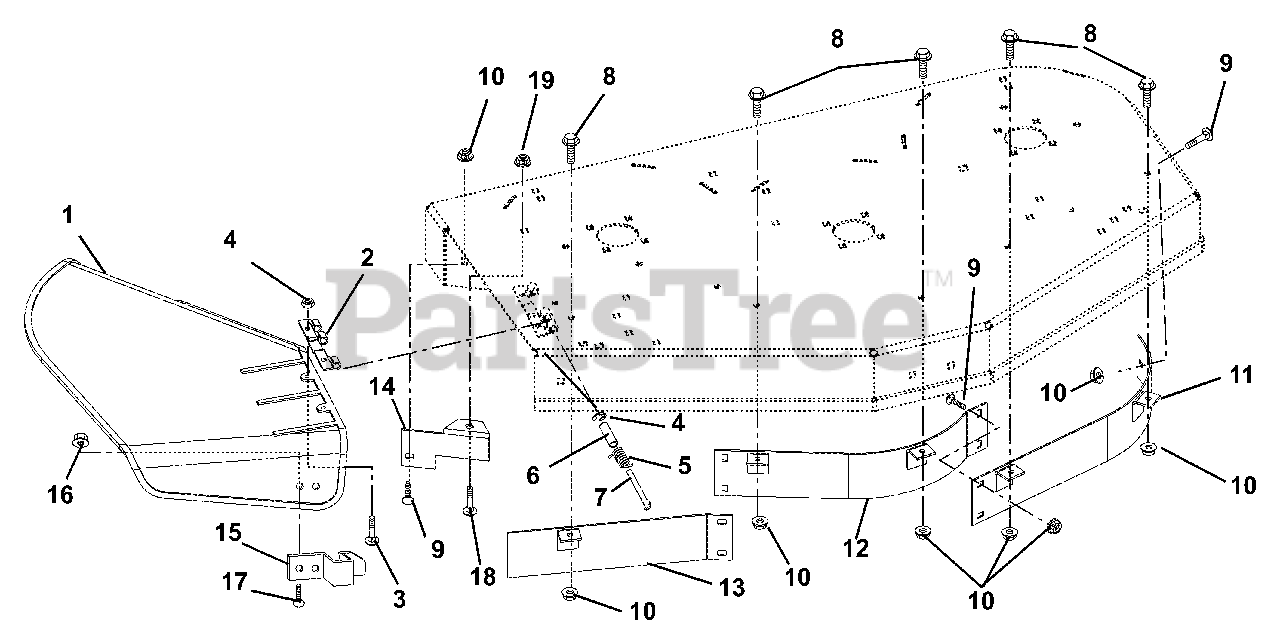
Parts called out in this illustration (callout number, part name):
1	Deflector, Chute
2	Hinge, Plate
3	Bolt, Round Head Square Neck .25-20 x .75 Grade 5
4	Ring, Retaining External .312 x .025
5	Spring, Torsion .095 x .50 x 1.00
6	Bushing, Sleeve
8	Bolt, Serrated Hex Flange Washer Head .31-18 x .75
9	Bolt, Round Head Square Neck .31-18 x .75
10	Nut-.312-18 Flange Nyloc
11	Weldment, Upper Left Baffle-40" (044)
11	Weldment, Upper Left Baffle-44" (046)
11	Weldment, Upper Left Baffle-48" (048)
11	Weldment, Upper Left Baffle-52" (050)
12	Weldment, Upper Center Baffle-40" (044)
12	Weldment, Upper Center Baffle-44" (046)
12	Weldment, Upper Center Baffle-48" (048)
12	Weldment, Upper Center Baffle-52" (050)
13	Weldment, Upper Right Baffle-40" (044)
13	Weldment, Upper Right Baffle-44" (046)
13	Weldment, Upper Right Baffle-48" (048)
13	Weldment, Upper Right Baffle-52" (050)
14	Deflector, 40" (044)
14	Deflector, 44"/48" (046, 048)
14	Deflector, 52" (050)
15	Flat Spring
16	Nut, Locking Top Flange .25-20
17	Bolt, Round Head Square Neck .25-20 x .50 Grade 5
18	Bolt, Round Head Square Neck .38-16 x 1.00 Grade 5
19	Nut, Flange Nyloc .375-18
